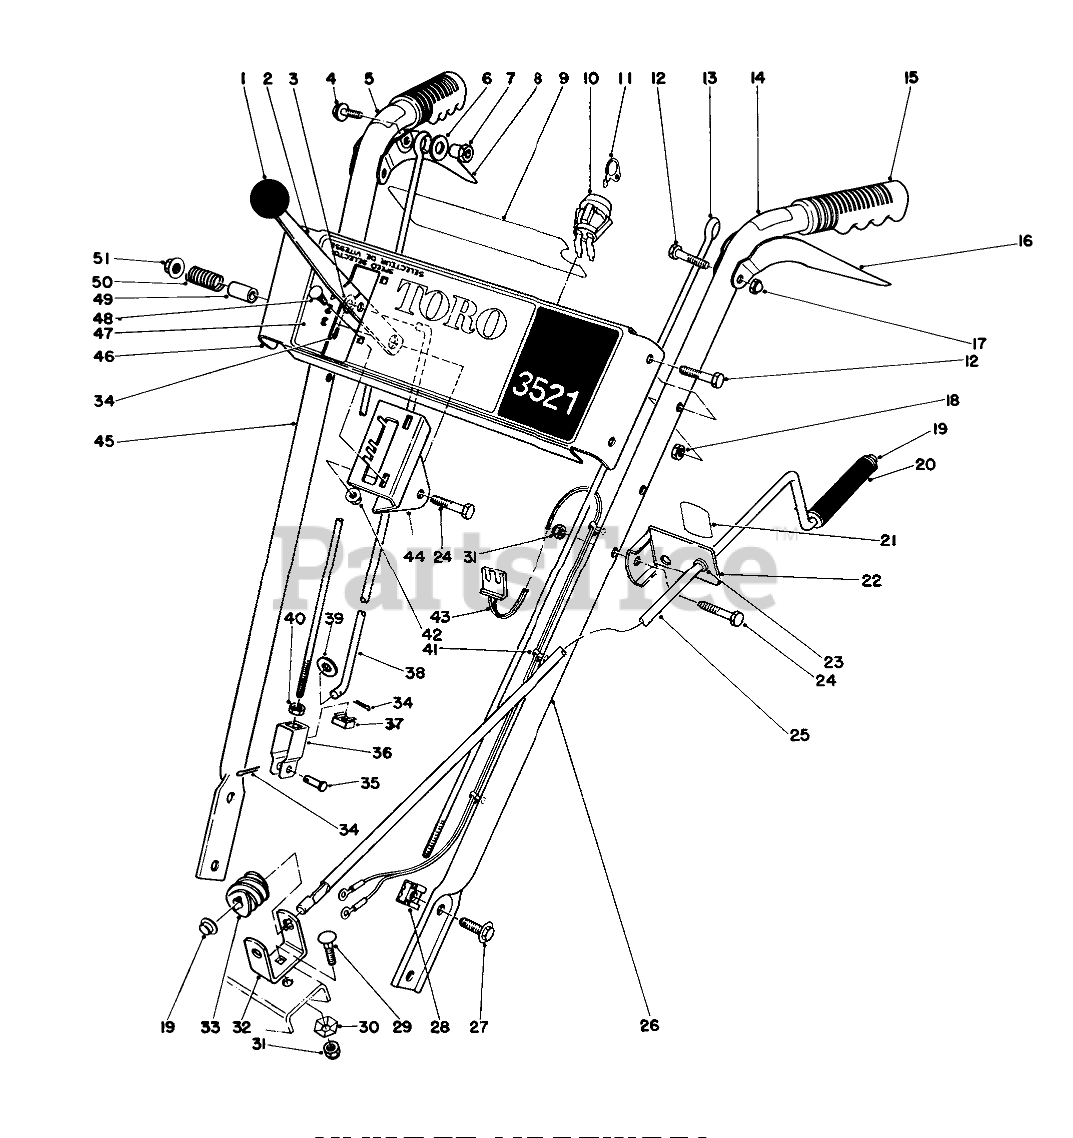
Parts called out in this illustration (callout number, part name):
2	SPEED SELECTOR B
3	WASHER-FLAT
4	SCREW-HHF
5	Decal-Auger Drive
6	WASHER-FLAT
7	POST-MOUNTING, LINKAGE
8	Lever-Auger Control
9	Decal-Escutcheon Back
10	SWITCH
11	Key
12	SCREW-HH
14	Decal-Wheel Drive
15	Grip
16	Lever-Traction Control
17	NUT-CAP
18	NUT-LOCK, CONE
19	RETAINER-PUSH ON
20	GRIP-CONTROL, CHUTE
21	CHUTE DECAL
22	Bracket-Chute Control Mounting (Incl. Ref. #21 & 23)
23	Bushing
24	SCREW-HH
25	ROD-CONTROL, CHUTE
26	Handle Left
27	SCREW-HHF
29	BOLT-CARR
30	WASHER-LOCK
31	NUT-LOCK, NI
32	BRACKET-WORM
33	GEAR-WORM, CHUTE
34	SCREW-HSH
35	PIN-CLEVIS
36	CLEVIS
37	NUT-RETAINED
38	ROD-SELECTOR, SPEED
39	WASHER-PLAIN
40	NUT-JAM
41	Mount-Wire
42	NUT-HHF
43	WIRE HARNESS
44	Mount-Speed Selector
45	Handle Ring
46	ESCUTCHEON PLT B
47	Decal-Escutcheon
48	SCREW-CARRIAGE
49	SPACER
50	SPRING
51	NUT-HF
